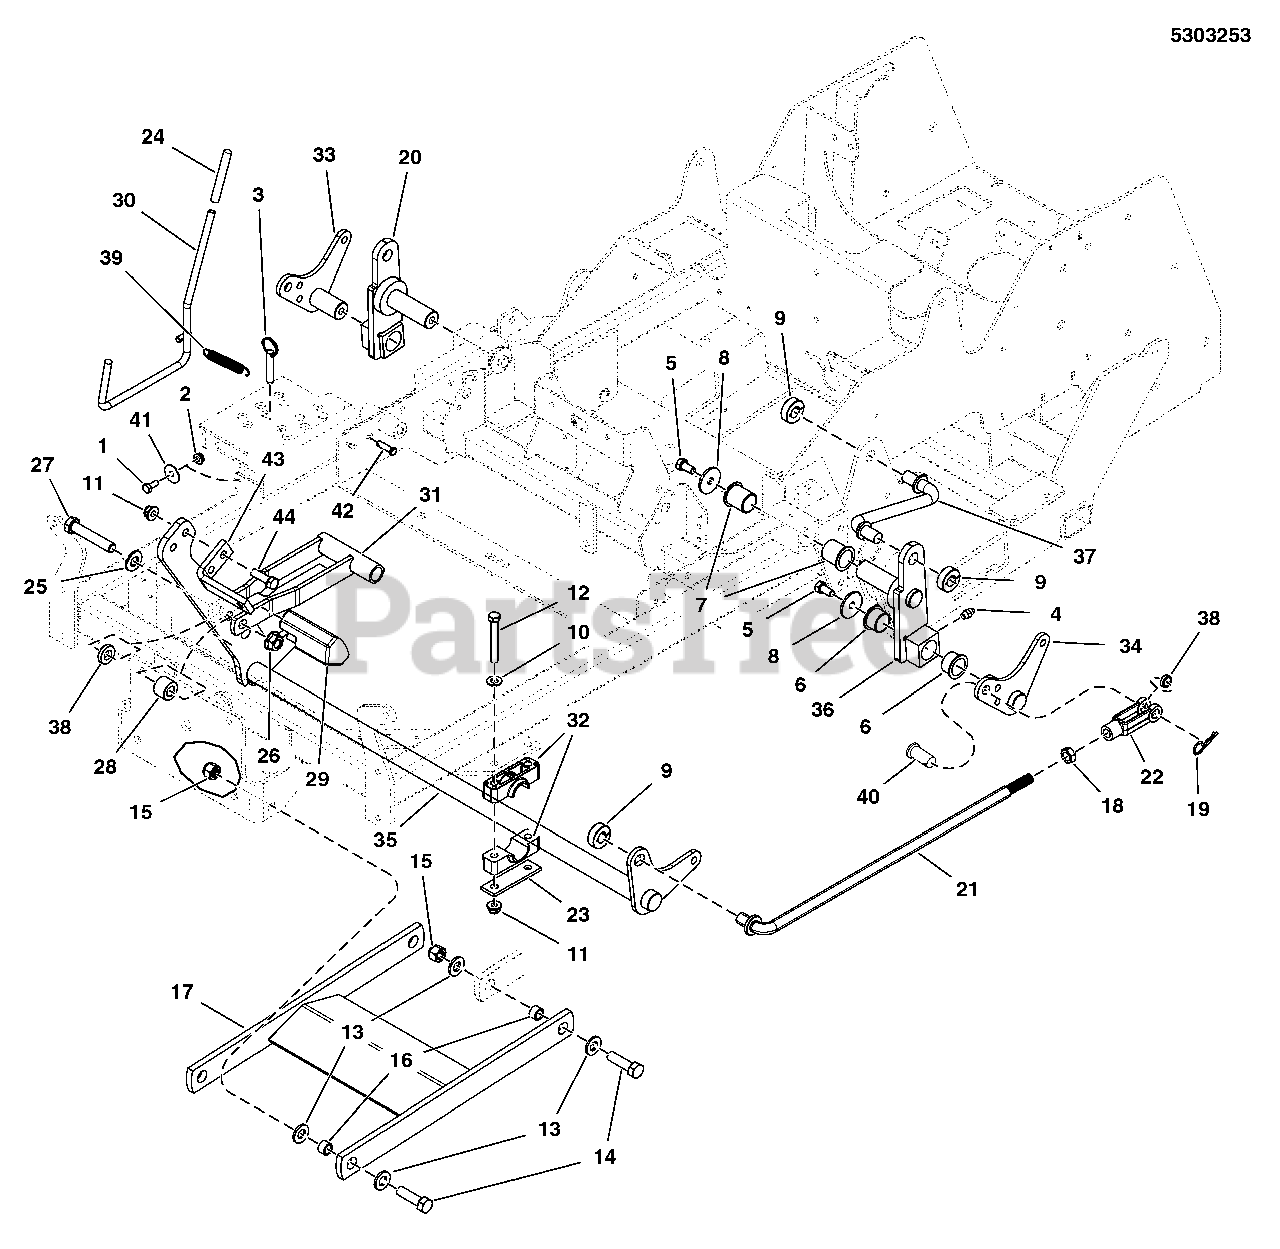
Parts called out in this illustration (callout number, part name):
1	BOLT,1/4-20X5/8
2	NUT, 1/4-20 HEX SERR. FLANGE
3	PIN, HITCH, 1/2 X 2.00 OAL, YP
4	GREASE FITTING, 1/4-28 STRAIGHT
5	BOLT, 3/8-16 X 3/4, GD5, YZ WITH PATCH
6	BUSHING, 1.00X1.13X.75, PLA
7	BUSHING, 1.00 X 1.13 X 1.38, PLASTIC
8	WASHER, .390 X 1.50 X .109, YZ
9	COLLAR, 5/8 SPLIT
10	WASHER, 3/8 SAE
11	NUT, 3/8-16 HEX NYLOCK FLANGE
12	BOLT, 3/8-16 X 2-3/4 GD5 YZ
13	WASHER, 1/2 GD9 YZ
14	BOLT, 1/2-20 X 1-3/4 GD8 YZ
15	NUT, 1/2-20 HEX NYLON LOCK
16	INSERT, BEARING
17	WELD, PULLER BAR, IS600 - BLK
18	NUT, 1/2-20 HEX JAM
19	PIN, HAIR, .0915 X 1-7/8
20	WELD, REAR LIFT - RH - IS500Z - BLK
21	ROD, DECK LIFT, SNP
22	CLEVIS, 1/2-20, STEEL, CLEAR ZINC
23	PLATE, PIVOT BLOCK SUPPORT - BLK
24	GRIP, FOAM, .475 X 4.35 X .095
25	WASHER, 1/2 SAE
26	NUT, 1/2-13 HEX NYLOCK FLANGE
27	BOLT, 1/2-13 X 2-3/4 GD5 YZ
28	SPACER, .52 X 1.00 X .75, CZ
29	RUBBER, FOOT PEDAL
30	WELD, ROD DECK LIFT, IS700 - BLK
31	WELD, DECK HEIGHT LINK, IS700 - RED
32	PIVOT BLOCK, PLASTIC
33	WELD, HANGER, REAR, RH - BLK
34	WELD, HANGER, REAR, LH - BLK
35	WELD, DECK LIFT SHAFT, IS600
36	WELD, REAR LIFT - LH - IS500Z - BLK
37	ROD, SUSPENSION LINK, IS600
38	SPACER, .52 X 1.00 X .22, CZ
39	SPRING-EXT, .740 ODX2.025LGX.072WR, BLK
40	CLEVIS PIN, 1/2 X 1.3 SAE STANDARD
41	WASHER, 1/4 FENDER
42	CLEVIS PIN, 1/4 X 1/2, CZ
43	PEDAL, FOOT - BLK
44	BOLT, 3/8-16 X 1-1/4 GD5
